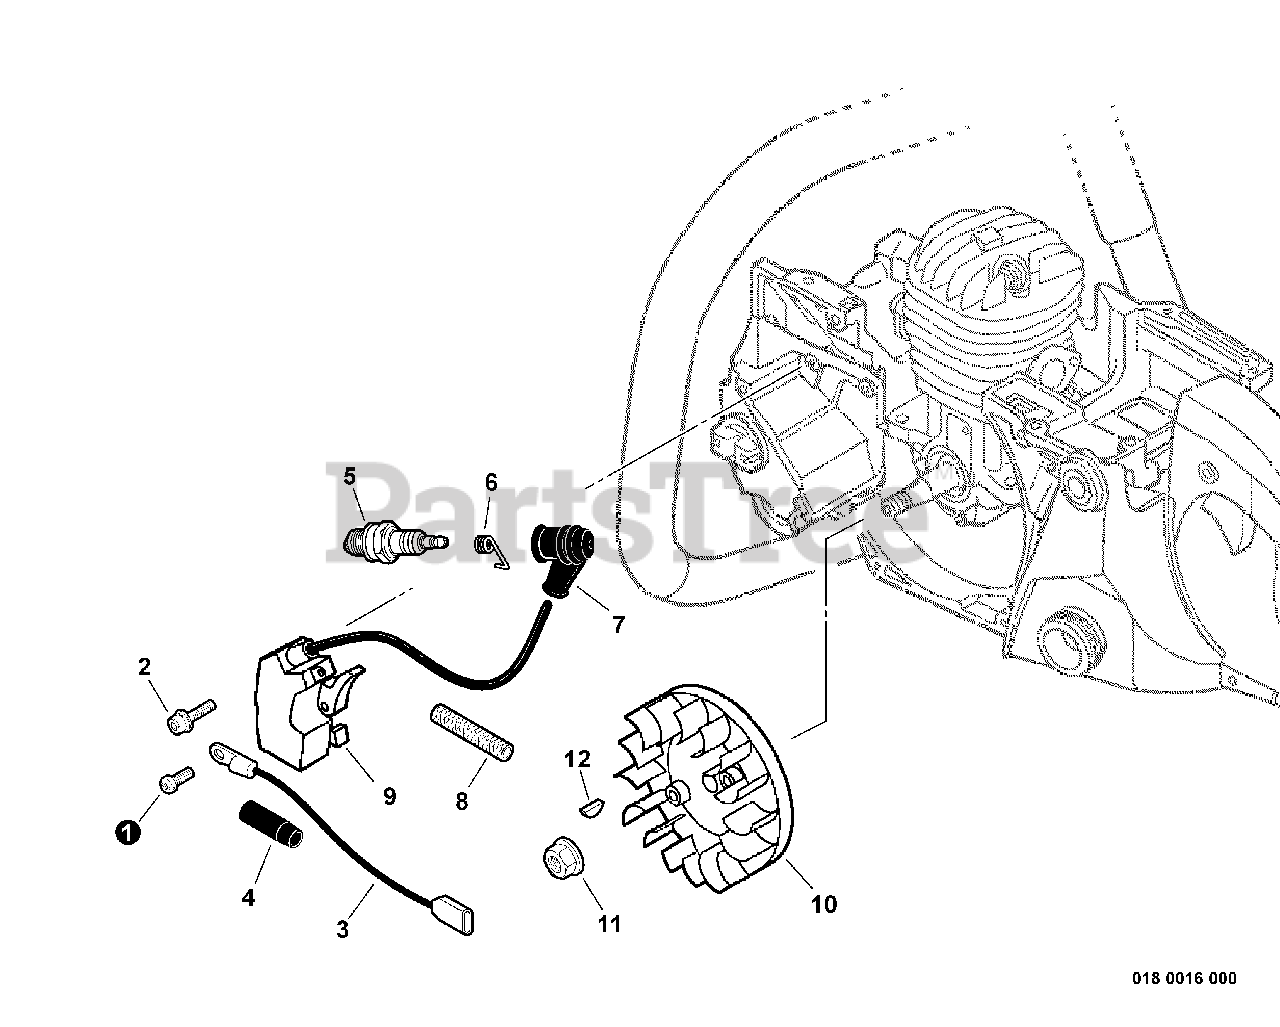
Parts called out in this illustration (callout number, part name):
1	SCREW - 4X6
2	SCREW - 4X30
3	LEAD - GROUND
4	BOOT, CONNECTOR
5	SPARK PLUG -- BPM-8Y
5	SPARK PLUG -- BPMR-8Y
6	TERMINAL, SPARK PLUG CAP
7	CAP, SPARK PLUG
8	TUBE, INSULATOR
9	COIL, IGNITION
10	FLYWHEEL
11	NUT - 8 -- FLANGE
